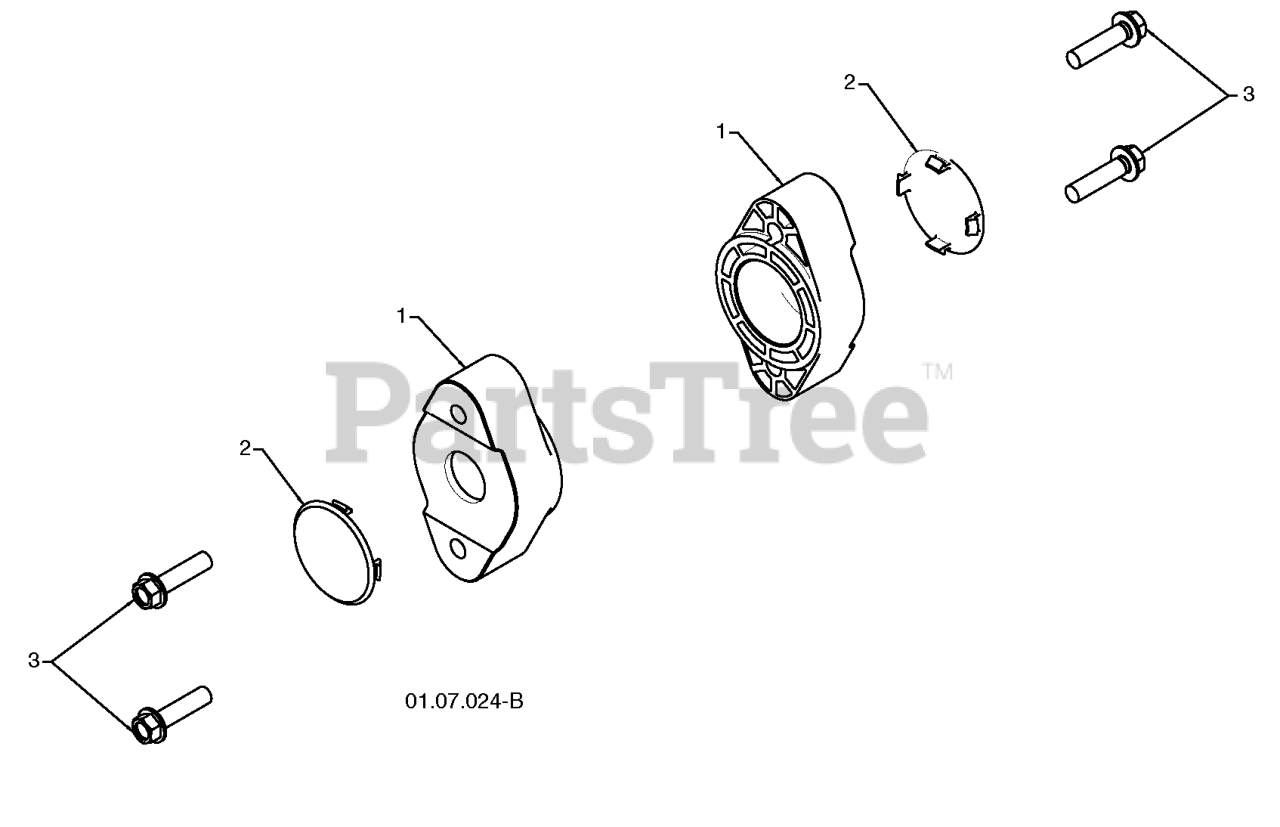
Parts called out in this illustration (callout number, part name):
1	BEARING.AUGER.SHAFT
2	PLUG.BEARING.HOLE.HSG
3	SCREW, HEX HD 5/16X1
